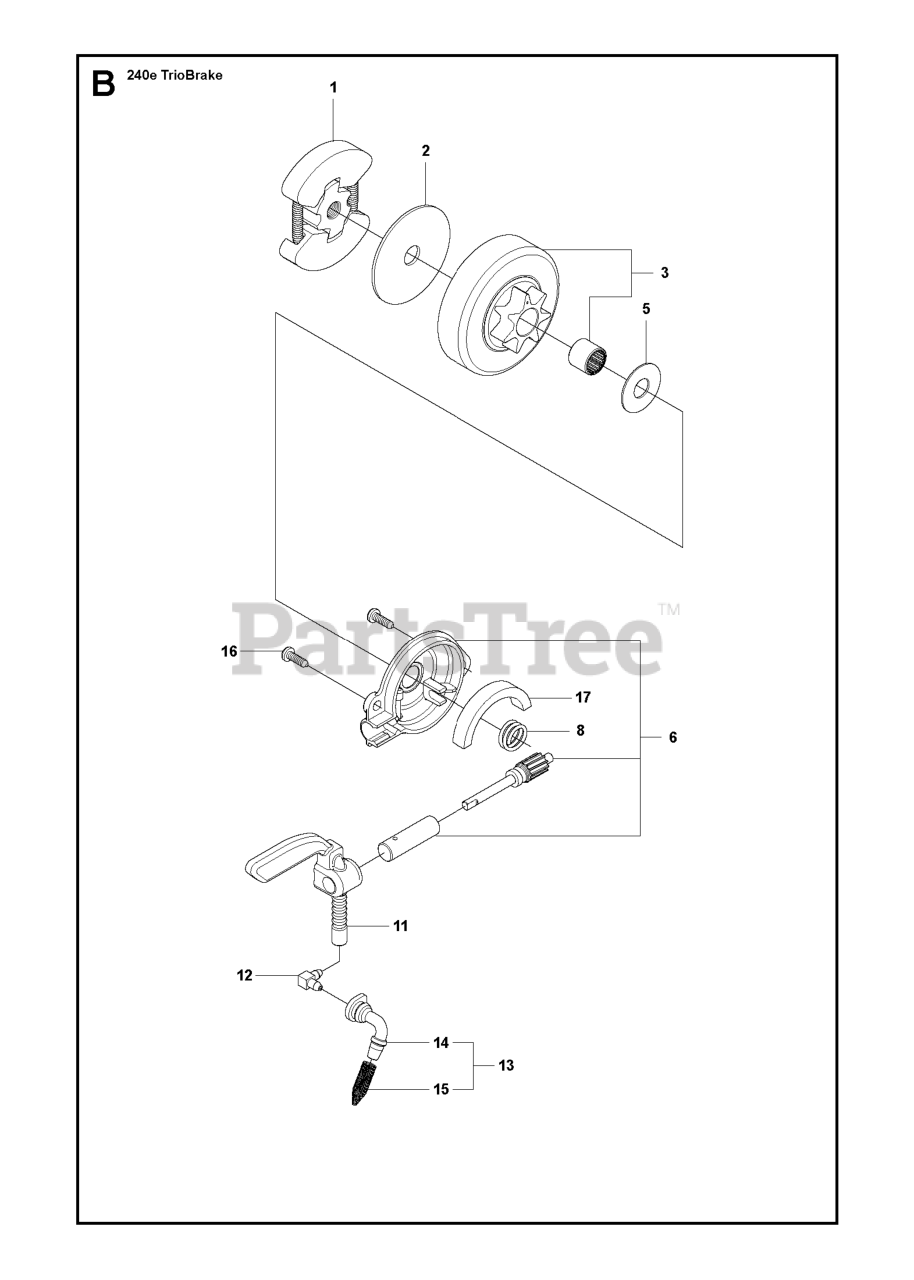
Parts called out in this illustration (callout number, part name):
1	CLUTCH ASSEMBLY
2	FRICTION DISC,CLUTCH 36/41
3	ASSY CLUTCH DRUM .325"
3	CLUTCH DRUM ASSY
6	OIL PUMP COMPLETE
13	PICK UPS ASSY OIL TANK
14	SEAL PICKUP
15	SCREEN/FILTER
16	SCREW 6-19X.437
